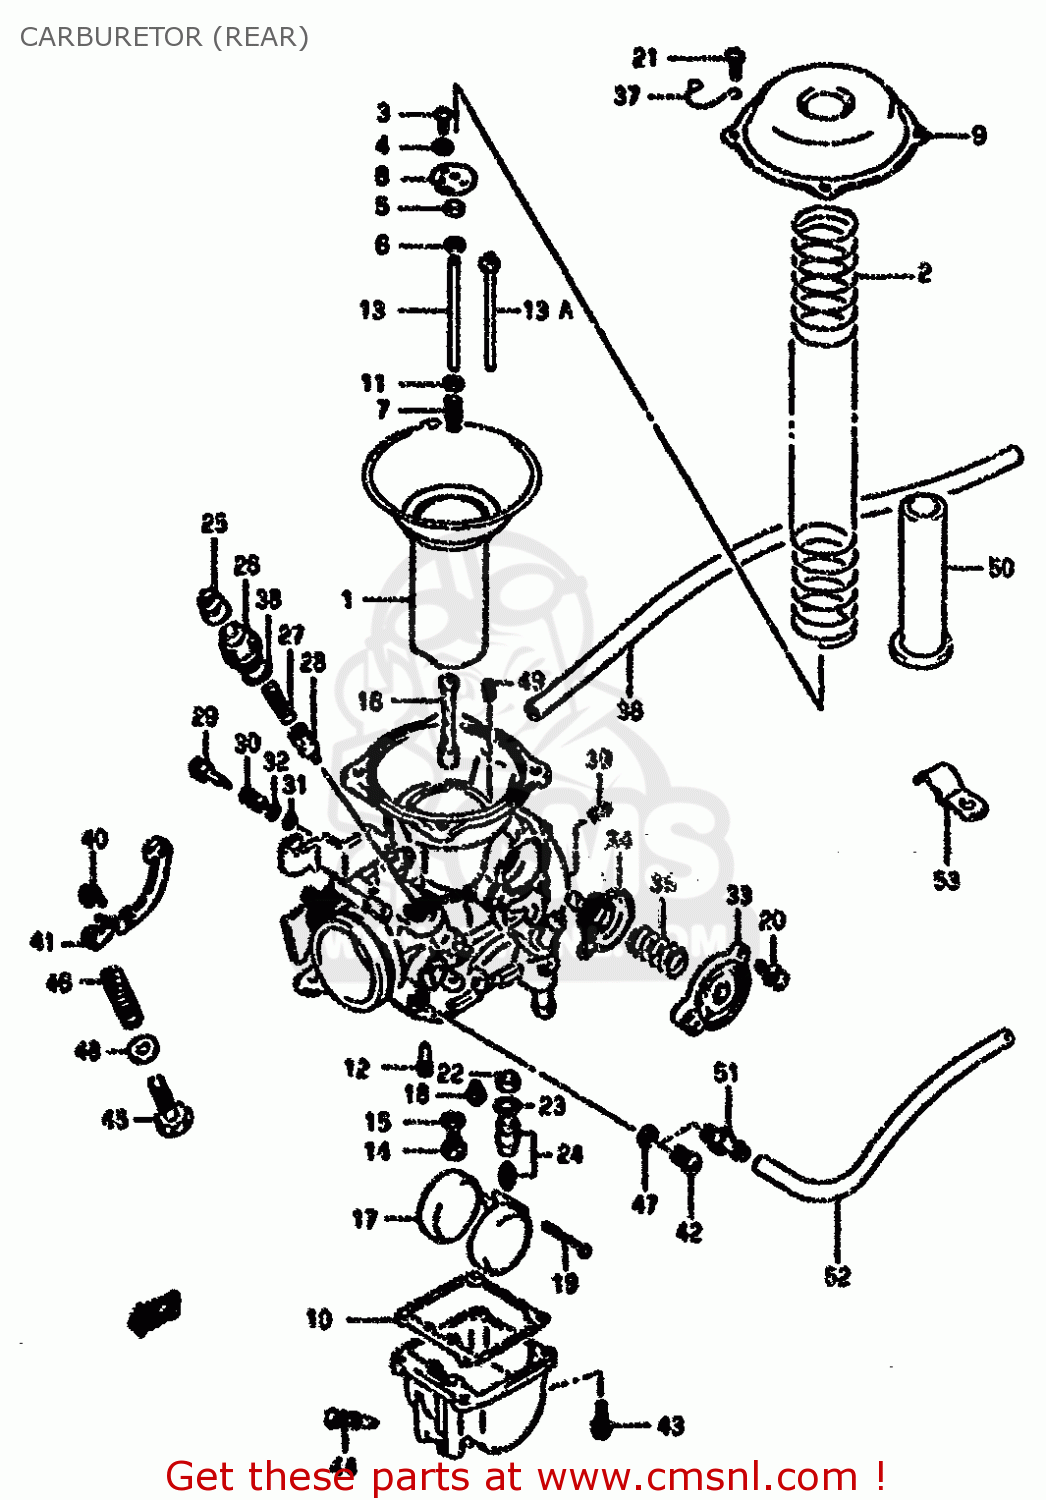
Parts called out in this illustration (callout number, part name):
1	DIAPHRAGM ASSY
2	SPRING,DIAPHRAGM
3	SCREW
4	WASHER,LOCK
5	RING
6	CLIP
7	SPRING
8	PLATE
9	COVER
10	GASKET,FLOAT CHAMBER (NAS)
11	WASHER
12	JET,PILOT(45)
13	NEEDLE,JET
13A	NEEDLE,JET (5F10)
14	JET,MAIN(135)
15	WASHER,NEEDLE NOZZLE
16	JET,NEEDLE (P-4)
17	FLOAT
18	SCREW
19	PIN,FLOAT
20	SCREW
21	SCREW
22	FILTER
23	O-RING,NEEDLE VALVE
24	VALVE ASSY,NEEDLE
25	CAP
26	HOLDER,GUIDE
27	SPRING
28	PLUNGER,STARTER
29	SCREW,PILOT
30	SPRING
31	O RING,PILOT AIR SCREW
32	WASHER
33	COVER
34	DIAPHRAGM ASSY
35	SPRING
36	HOSE(5X8.2X600)
37	CLIP
38	O RING
39	JET,PILOT
40	SCREW
41	LEVER ASSY
42	SCREW
43	SCREW
44	SCREW,DRAIN
45	ADJUSTER,THROTTLE
46	SPRING
47	GASKET,DRAIN PLUG (NAS)
48	WASHER
49	JET,PILOT AIR,1
50	RING
51	NIPPLE
52	HOSE (4.5X8.5X600)
53	CLAMP
